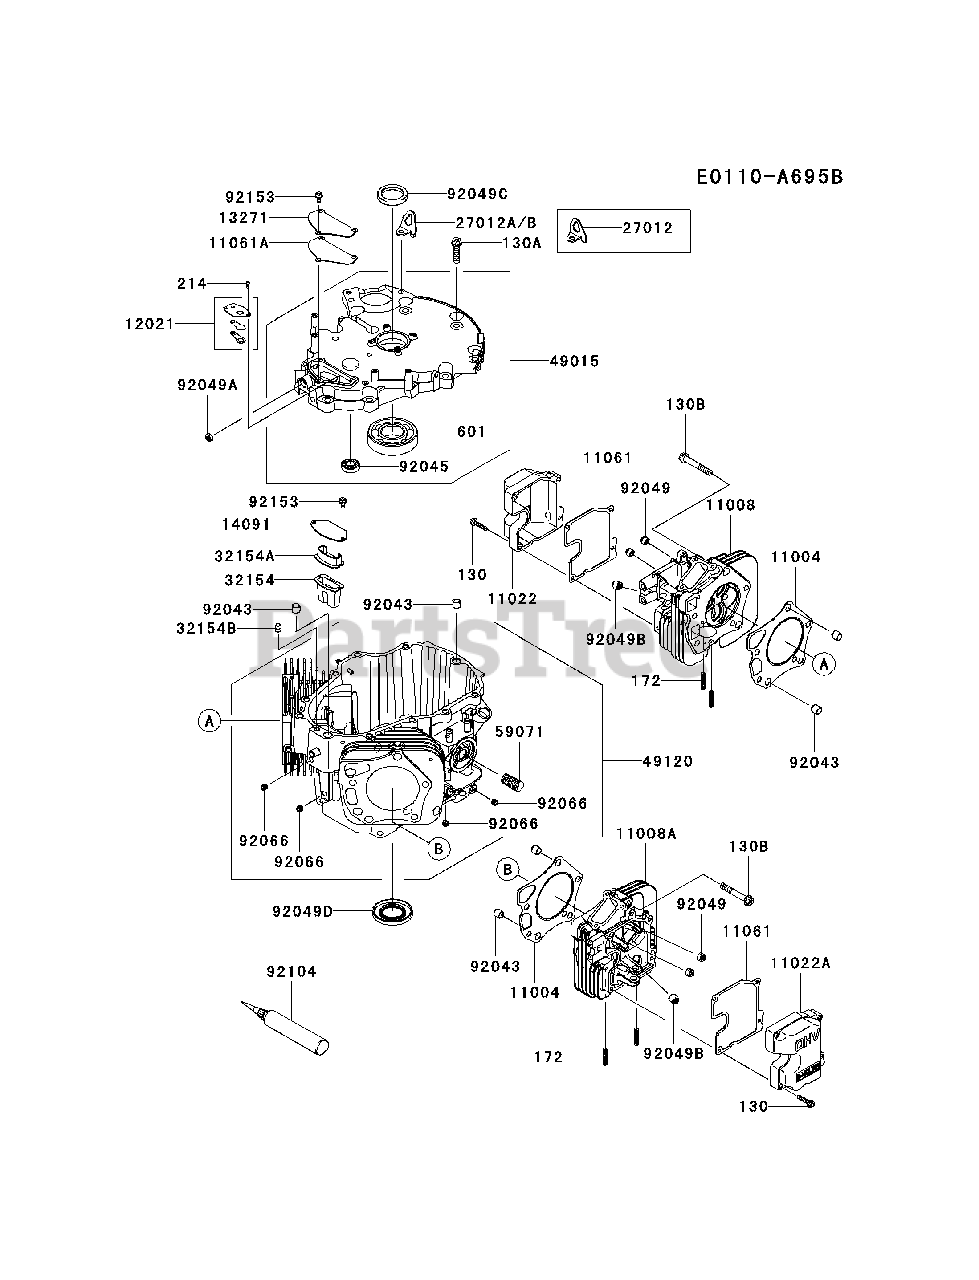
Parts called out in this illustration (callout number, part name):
130	BOLT-FLANGED,6X30
130A	BOLT-FLANGED,10X40
130B	BOLT-FLANGED,10X65
172	BOLT-STUD,8X18
214	SCREW-PAN+-,4X8
601	BEARING-BALL
